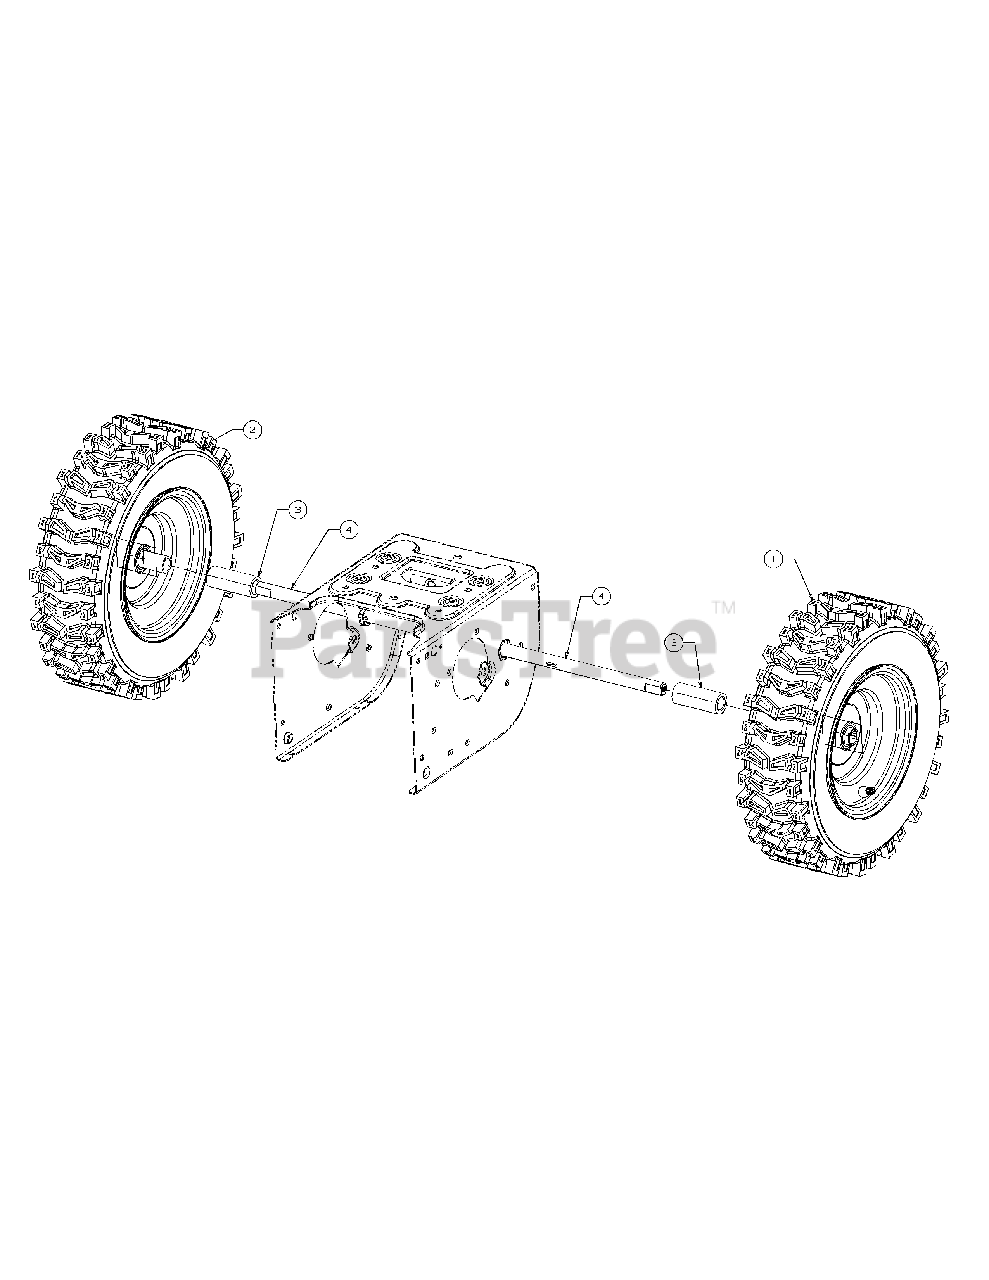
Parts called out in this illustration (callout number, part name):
1	Wheel Comp-LH X-Tra
2	Wheel Comp-RH X-Tra
3	Spacer-Wheel 1.25O
